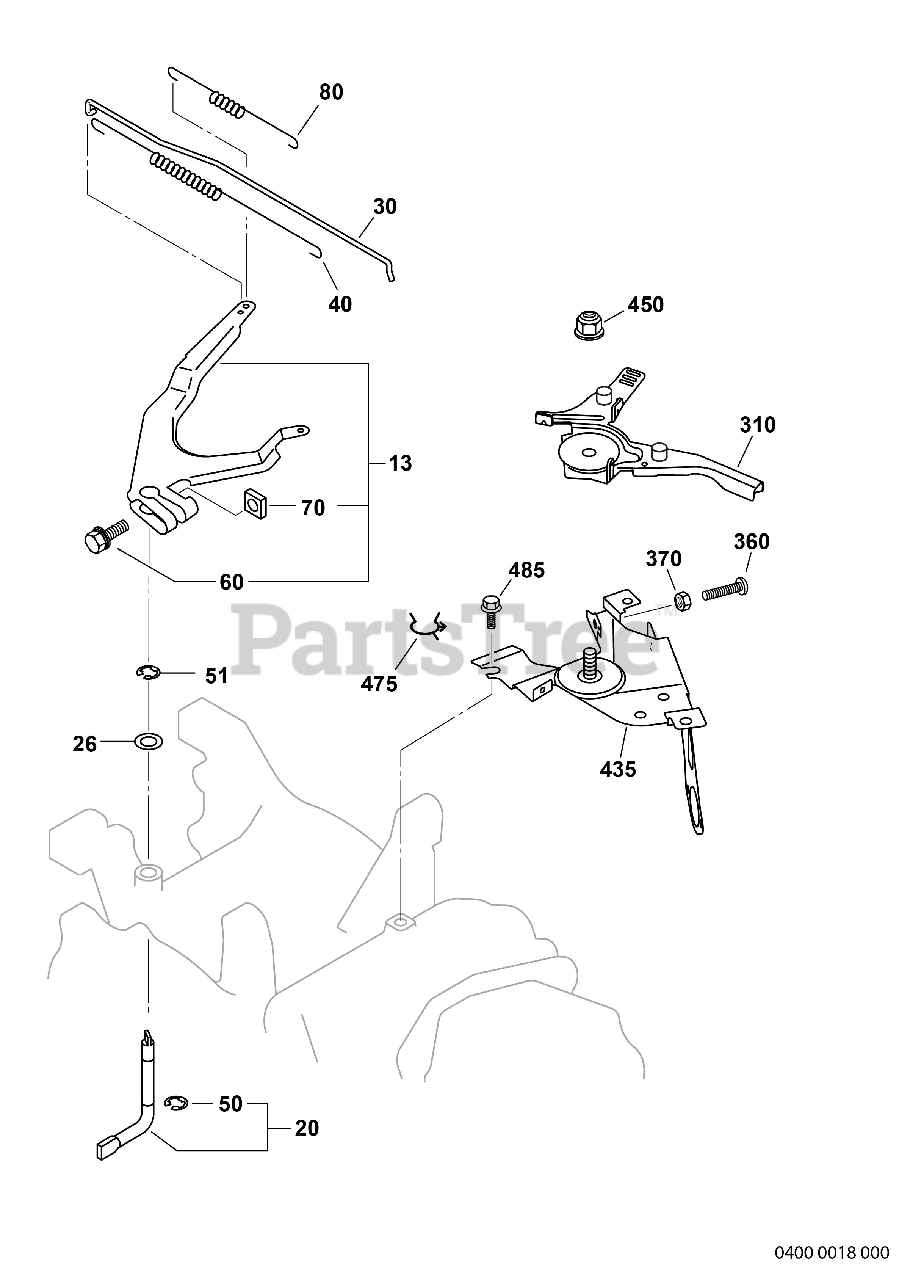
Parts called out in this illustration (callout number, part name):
13	GOVERNOR LEVER
20	GOVERNOR SHAFT CP
30	GOVERNOR ROD
60	BOLT AND WASHER AY
80	GOVERNOR SPRING
310	SPEED CONTROL LEVER
435	SPEED CONTROL BRACKET CP
